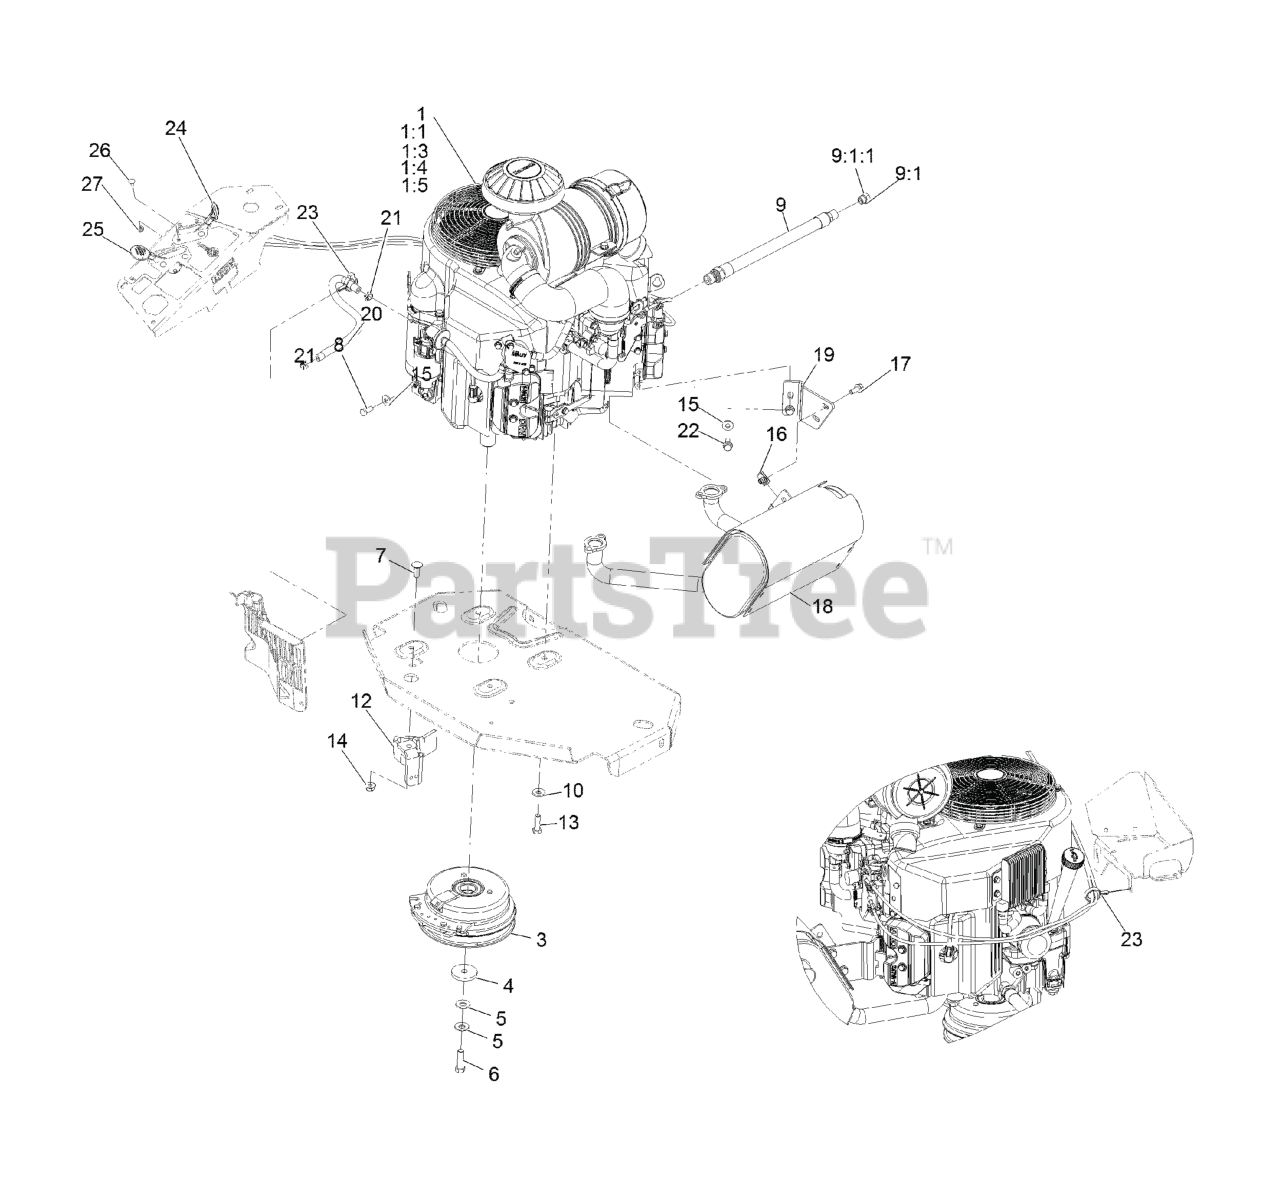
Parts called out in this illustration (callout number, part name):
1:1	Kawasaki 49065-2078 Engine Oil Filter
1:3	Kawasaki 49019-7001 Fuel Filter
1:4	Kawasaki 11013-7039 Safety Filter
1:5	Kawasaki 11013-7038 Air Filter
3	CLUTCH KIT
4	WASHER-CLUTCH
5	WASHER-SPRING
6	SCREW-HH 7/16-20 X 1 1/2 W/LOCTITE
7	SCREW-CARR
8	SCREW-HH
9	ENGINE OIL DRAIN HOSE ASM
9:1	PLUG-HH
9:1:1	O-RING
10	WASHER-BELLEVILLE
12	CLUTCH-ANCHOR
13	SCREW-HH
14	NUT-HF, NI
15	WASHER-SPRING
17	SCREW-HHF
18	MUFFLER
19	BRACKET-MUFFLER
20	HOSE-FUEL
21	CLAMP-HOSE
22	SCREW-HHF
23	CLAMP-HOSE
24	ASM, CHOKE CABLE
25	ASM,THROTTLE CABLE
26	BOLT-CARR
27	NUT-LOCK, NI
